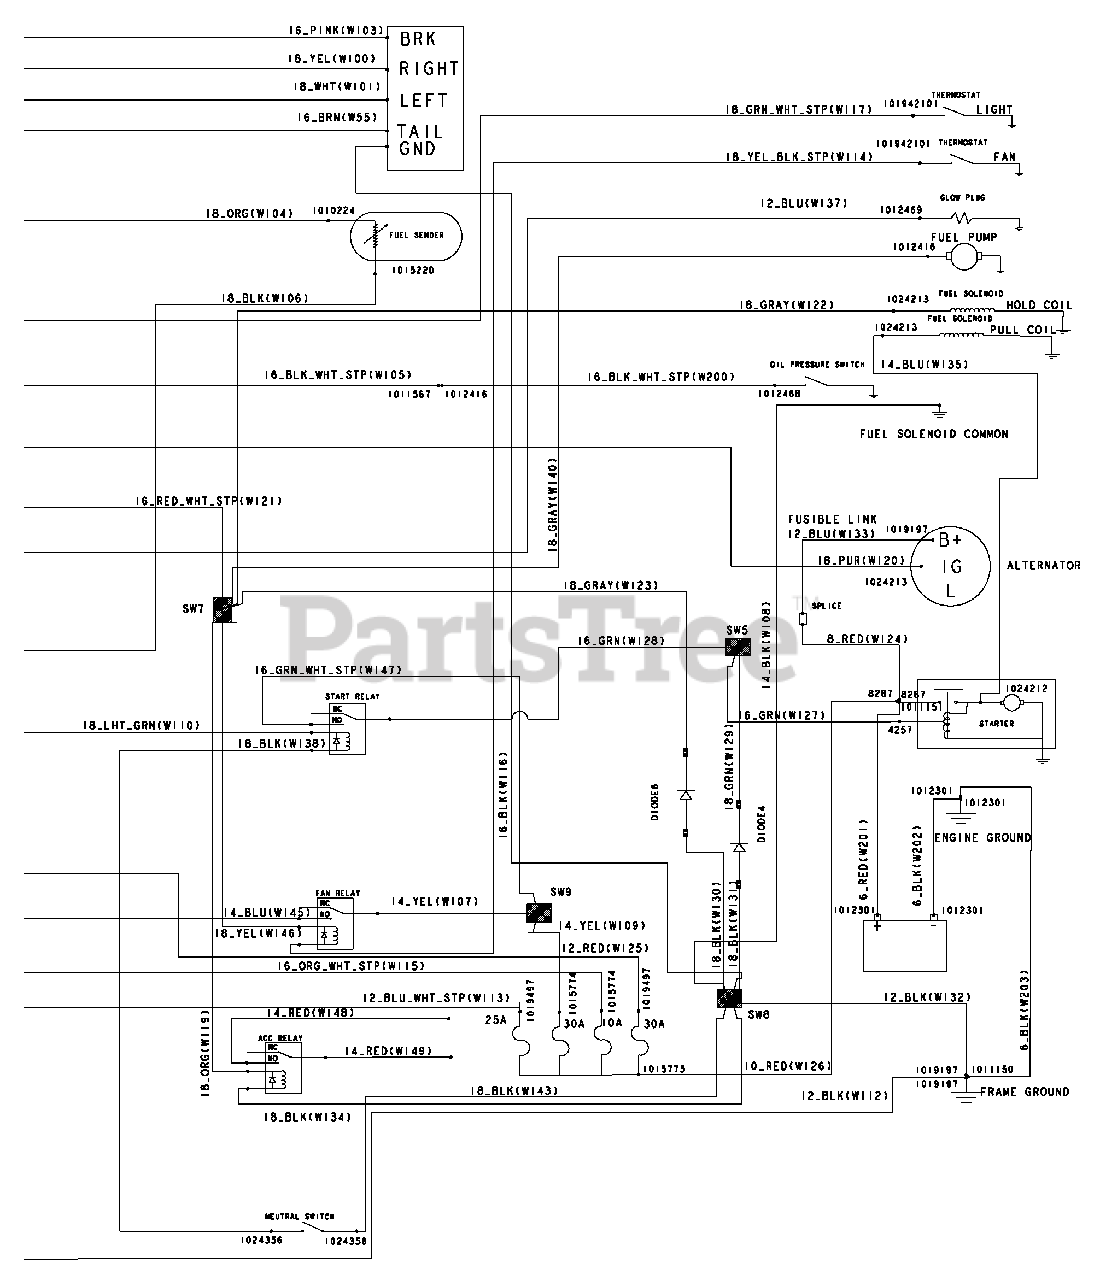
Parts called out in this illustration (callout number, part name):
1	Diode, General Purpose, 6.0a
2	Harness, Diesel, AWD, Stretch
3	Asm, Switch, Limit, Awd
